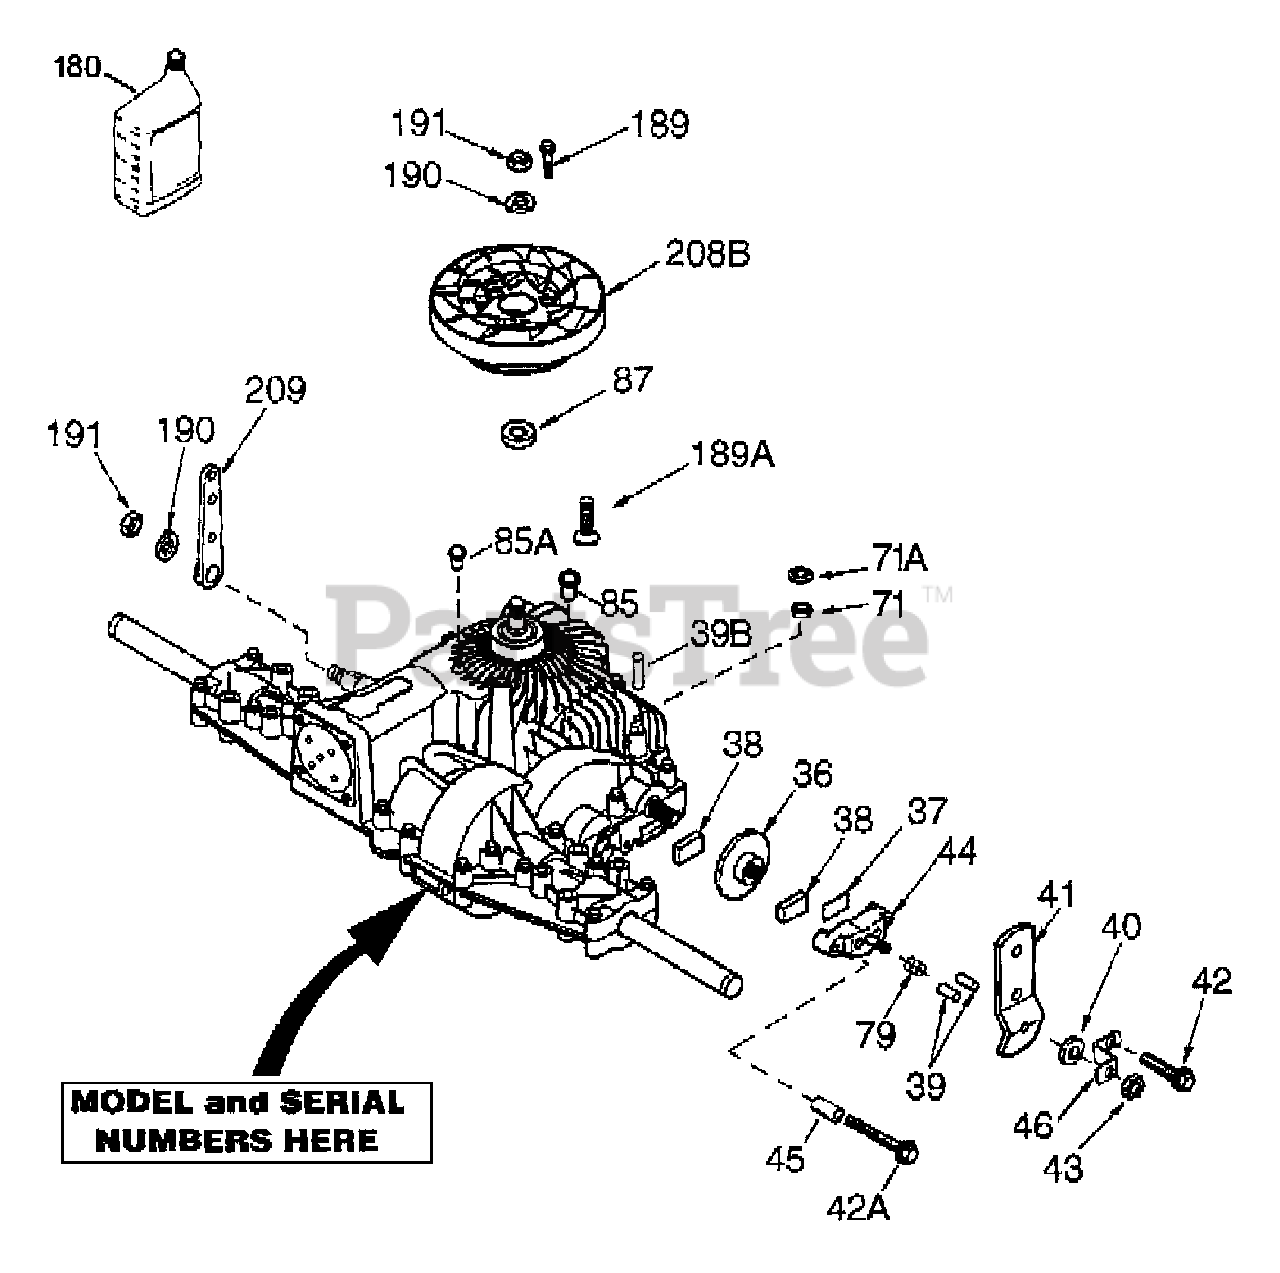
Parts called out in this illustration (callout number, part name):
36	Brake Disc
37	Brake Pad Plate
38	Brake Pad
39	Dowel Pin
39B	Belt Guard
40	Flat Washer
41B	Brake Lever
42	Screw, 1/4-20 x 1-1/4"
42A	Screw, 1/4-20 x 2-1/4"
43	Locknut, 5/16-24
44	Brake Pad Holder
46	Brake Lever Bracket
71	Square Cut Ring
71A	Pushnut, 9/16"
85	Oil Fill Plug
87	Oil Seal, 5/8"
180	Gear Oil 80W90
189	Drive Screw #6 x 1/2"
189A	Screw, 10-32 x 1/2"
190	Lockwasher
191	Nut, 7/16-20
208B	Fan/Coupling
209	Control Lever
